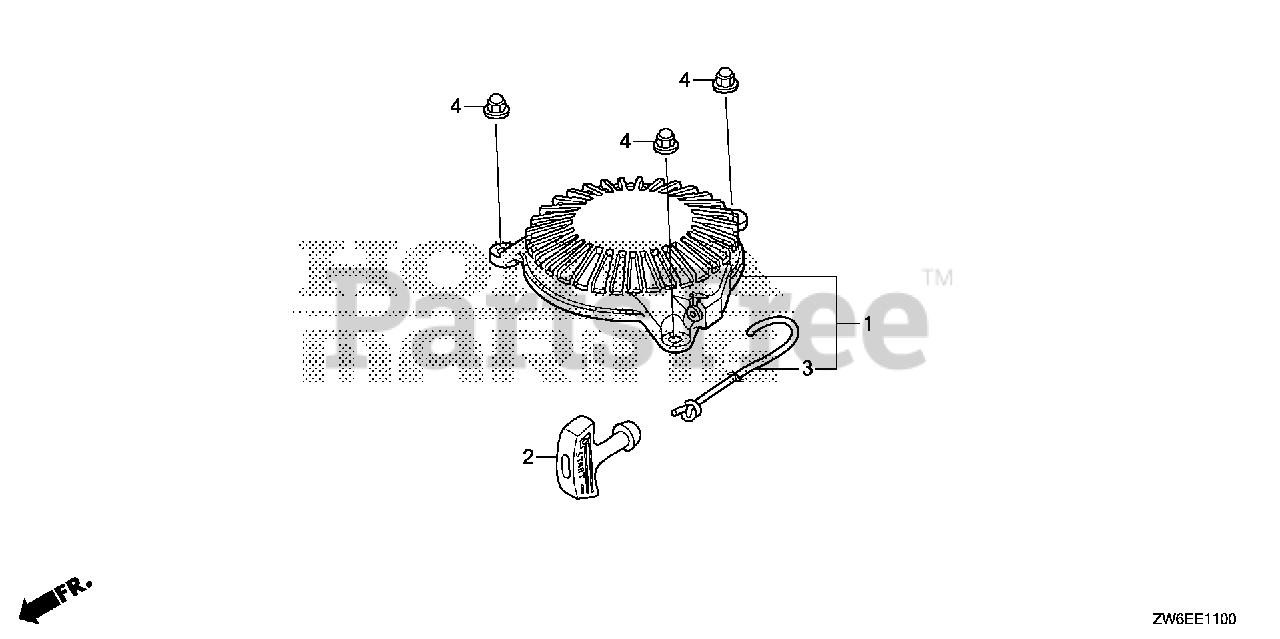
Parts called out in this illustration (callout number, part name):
1	STARTER ASSY., RECOIL
2	KNOB, STARTER
3	ROPE, RECOIL STARTER
4	NUT, FLANGE CAP (5MM)
